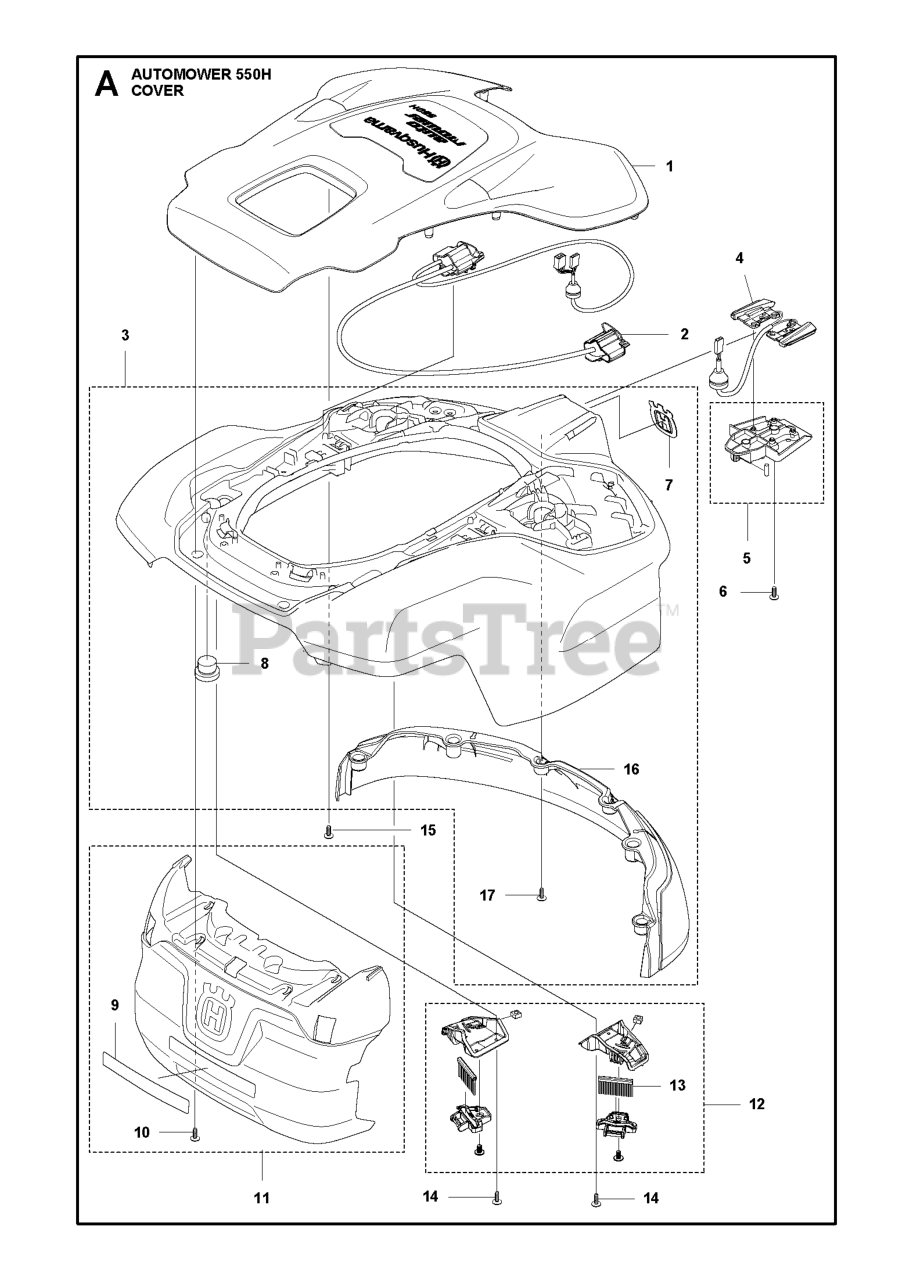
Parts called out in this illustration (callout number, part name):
1	Body
1	BODY KIT SPARE PART TOP COVER
2	WIRING ASSY ULTRASONIC
3	BODY ASSY 430XH, 450XH
4	CABLE ASSY CHARGING PLATE
5	HOLDER ASSY 430XH, 450XH
6	SCREW 14MM
7	DECAL HUSQVARNA CROWN HEIGHT 5
8	CAP SNAPLOC
9	LABEL WARNING P15
10	SCREW ITXPANT
11	BUMPER ASSY 430XH,450XH,550H
12	BRUSH KIT 430/450
13	WHEEL BRUSH REFILL KIT
14	SCREW ITXPANT
15	SCREW ITXPANT
16	BUMPER FRONT
17	SCREW ITXPANT
